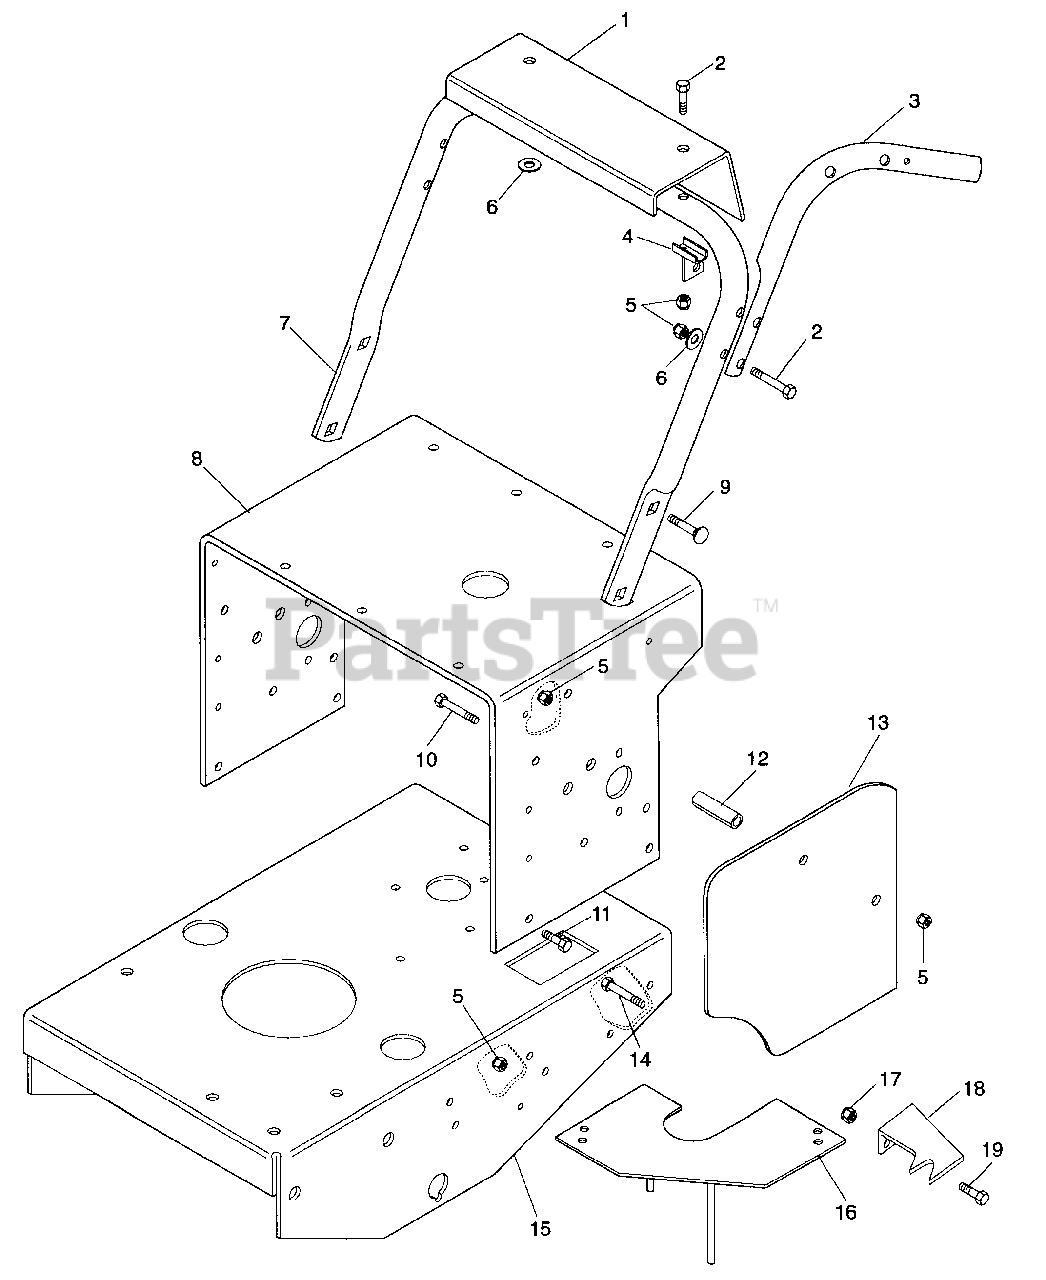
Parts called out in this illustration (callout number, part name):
1	Panel, Silk Screened
2	Bolt-Hex .38-16 x 2.00 Grade 5
3	Handlebar Left Hand
4	PTO Lever Mounting Bracket
5	Nut-Locking-Nylon .375-16 Grade 2
6	Washer-Flat-Steel .406 x .812 x .065
7	Lower Handlebar, Pro 100
8	Pro-100 Top Frame
9	Bolt-Round Head Square Neck .38-16 x 1.0
10	Bolt-Hex .38-16 x 4.00
11	Bolt-Hex .38-16 x 1.00 Grade 5
12	Bushing, Spacer, 3.25 x 3/8 ID x 5/8 OD
13	Guard, Drive Pro-100 Side Cover
14	Bolt-Hex .38-16 x 1.38
15	Pro-100 Main Frame
16	Belt Brake Finger-Deck Clutch
17	Nut-Locking-Nylon .312-18 Grade 2
18	Cleaner, Pulley Groove Left Hand
19	Bolt-Hex .31-18 x .625
